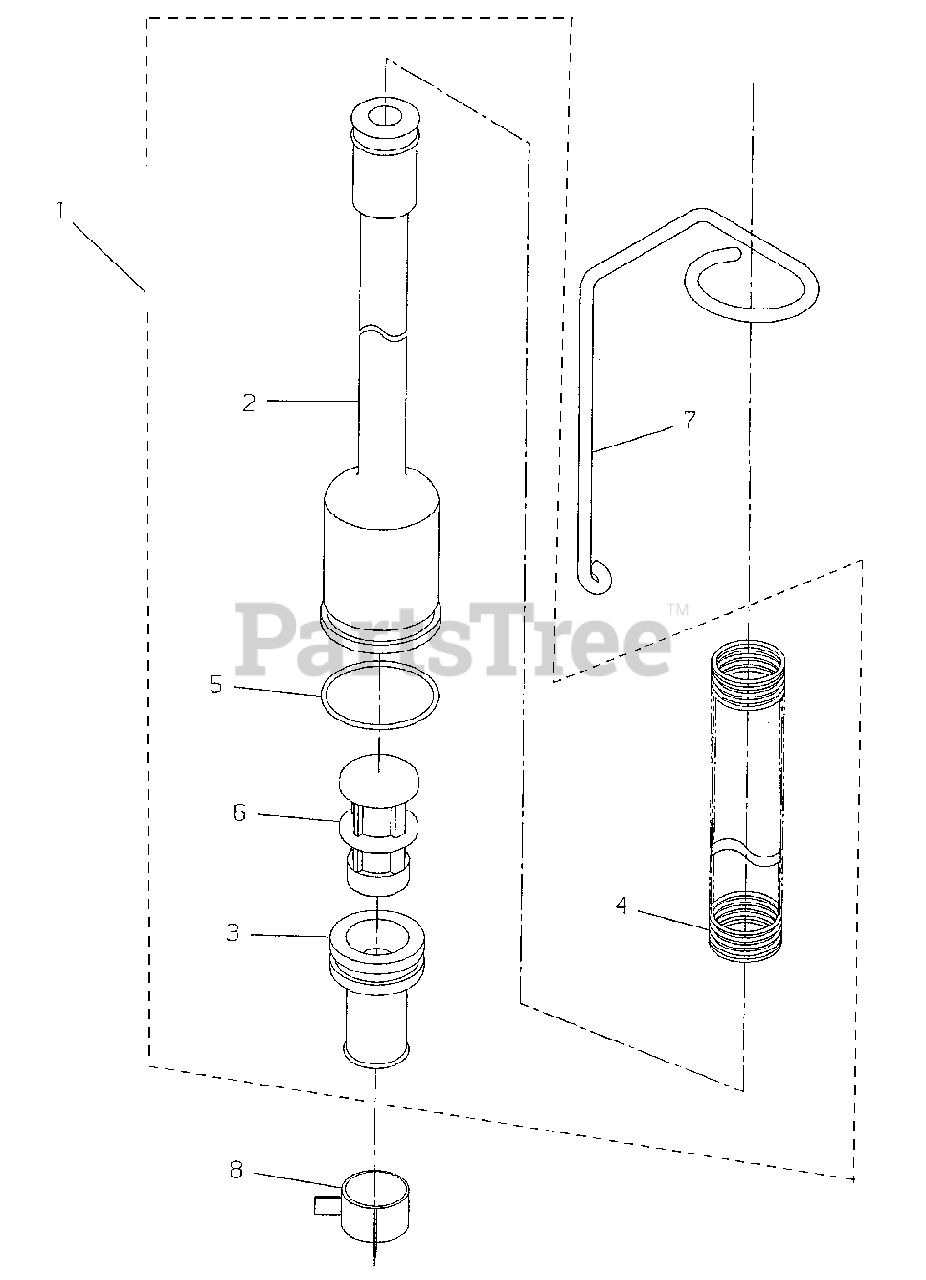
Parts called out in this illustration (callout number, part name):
1	FUEL FILTER ASSY
2	PIPE - FUEL
3	CONNECTOR
5	CLIP
6	FILTER, FUEL
7	HOLDER
8	CLAMP, HOSE
